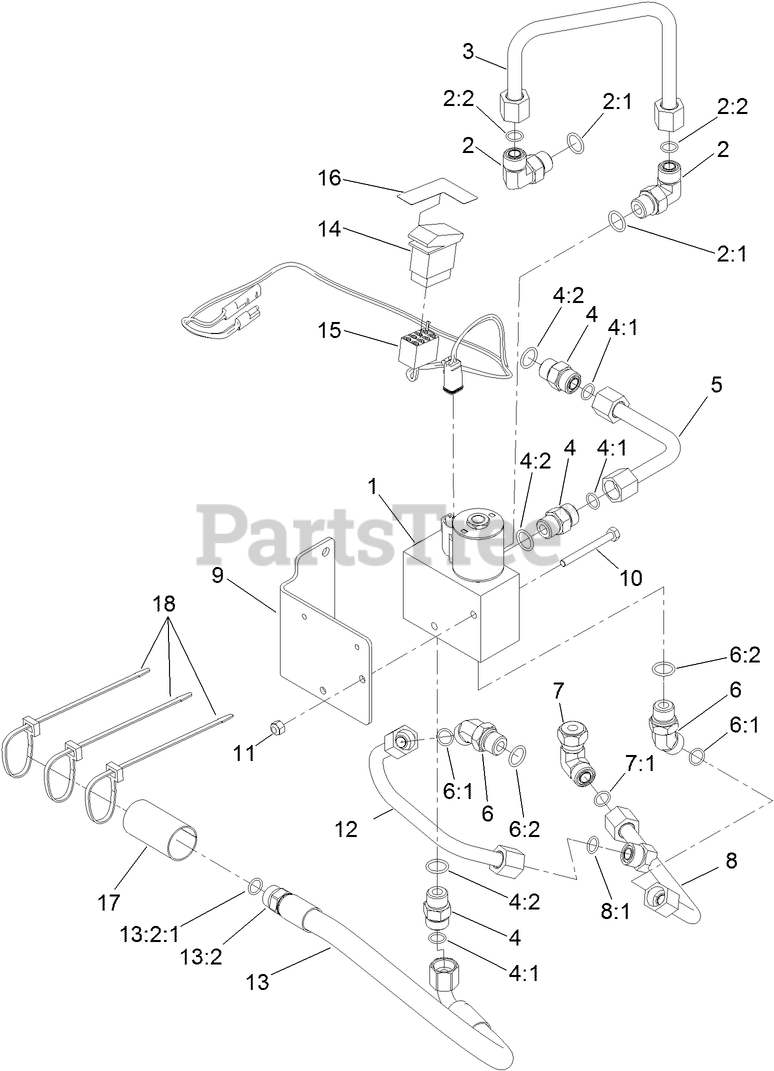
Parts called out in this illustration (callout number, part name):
1	VALVE-FLOW, LOW
2	FITTING-ELBOW-90 DEG
2:1	O-RING
2:2	O-RING
3	TUBE-HYD
4	FITTING-STRAIGHT
4:1	O-RING
4:2	O-RING
5	TUBE-HYD
6	FITTING-HYD, 45 DEG
6:1	O-RING
6:2	O-RING
7	FITTING-HYD
7:1	O-RING
8	HYD TUBE ASM
8:1	O-RING
10	SCREW-HH
11	NUT-LOCK, NI
12	TUBE-HYD
13	HYD HOSE ASM
13:2	FITTING-STRAIGHT
13:2:1	O-RING
14	SWITCH
15	HARNESS-WIRE, LOW FLOW
16	DECAL- LOW FLOW
17	PROTECTOR-HOSE
18	TIE-CABLE
